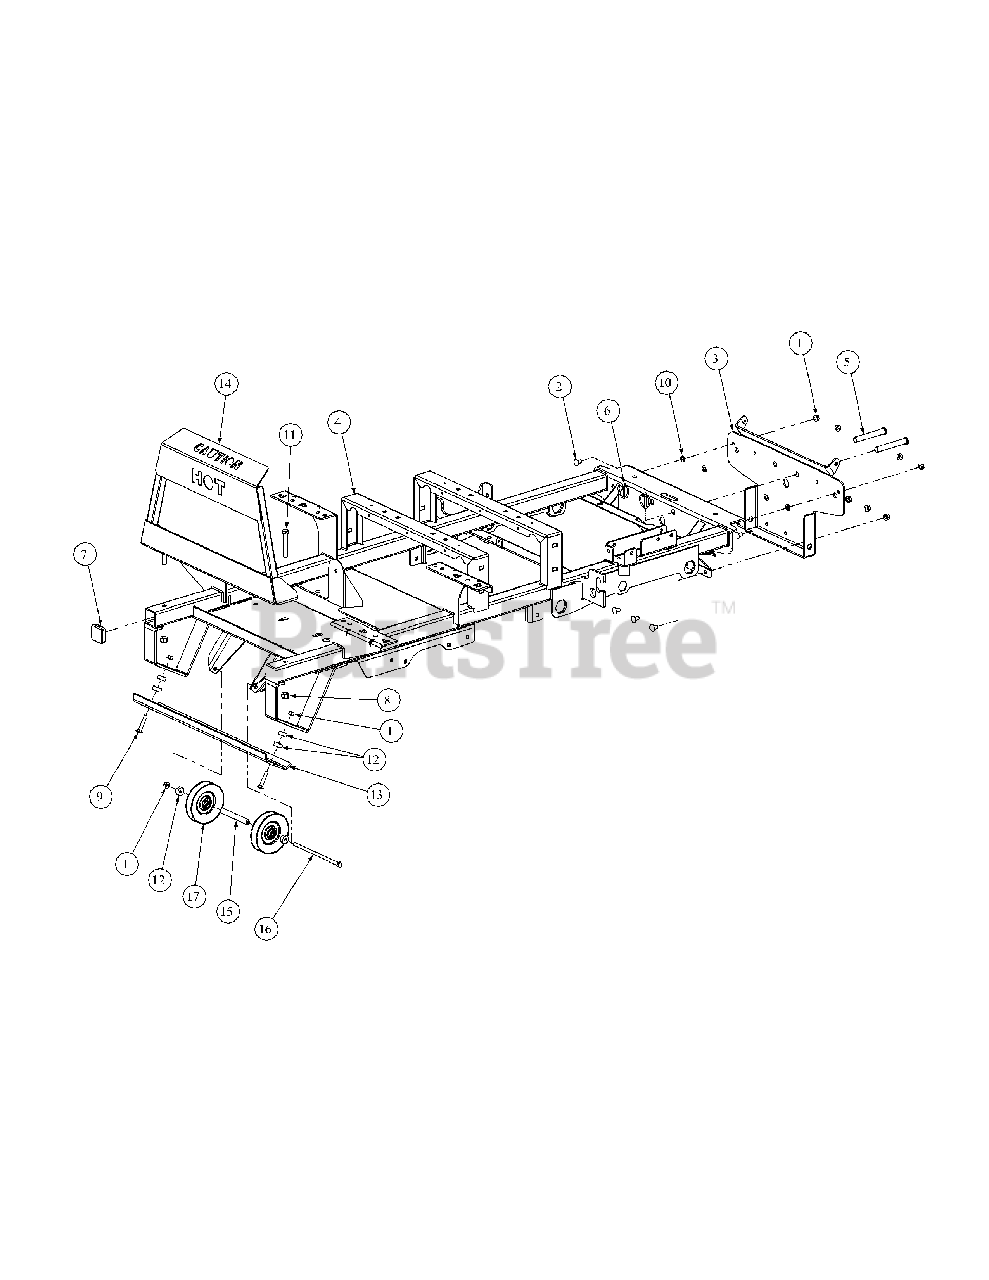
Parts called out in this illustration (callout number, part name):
1	Hex Nut, 3/8-16 Flange Lock
2	Carriage Bolt, 3/8-16 x .75 Long
3	Bracket Assembly, Frame, Front
4	Frame Assembly
5	Clevis Pin, .625 Dia x 4.375 Long
6	Linch Pin, 3/16 Dia.
7	Plug, Square Tube
8	Lock Nut, Nylon Insert, 1/2-13
9	Carriage Bolt, 3/8-16 x 2.00
10	Push Retainer, 3/8
11	Hex Head Cap Screw, 1/2-13 x 3.00
12	Spacer, .406 ID x 1.00 OD x .380
13	Guard Bracket
14	Muffler Guard Assembly
15	Spacer, .385 ID x .625 OD x 4.89
16	Hex Head Cap Screw, 3/8-16 x 8.50
17	Idler Pulley, 5.06 Dia.
